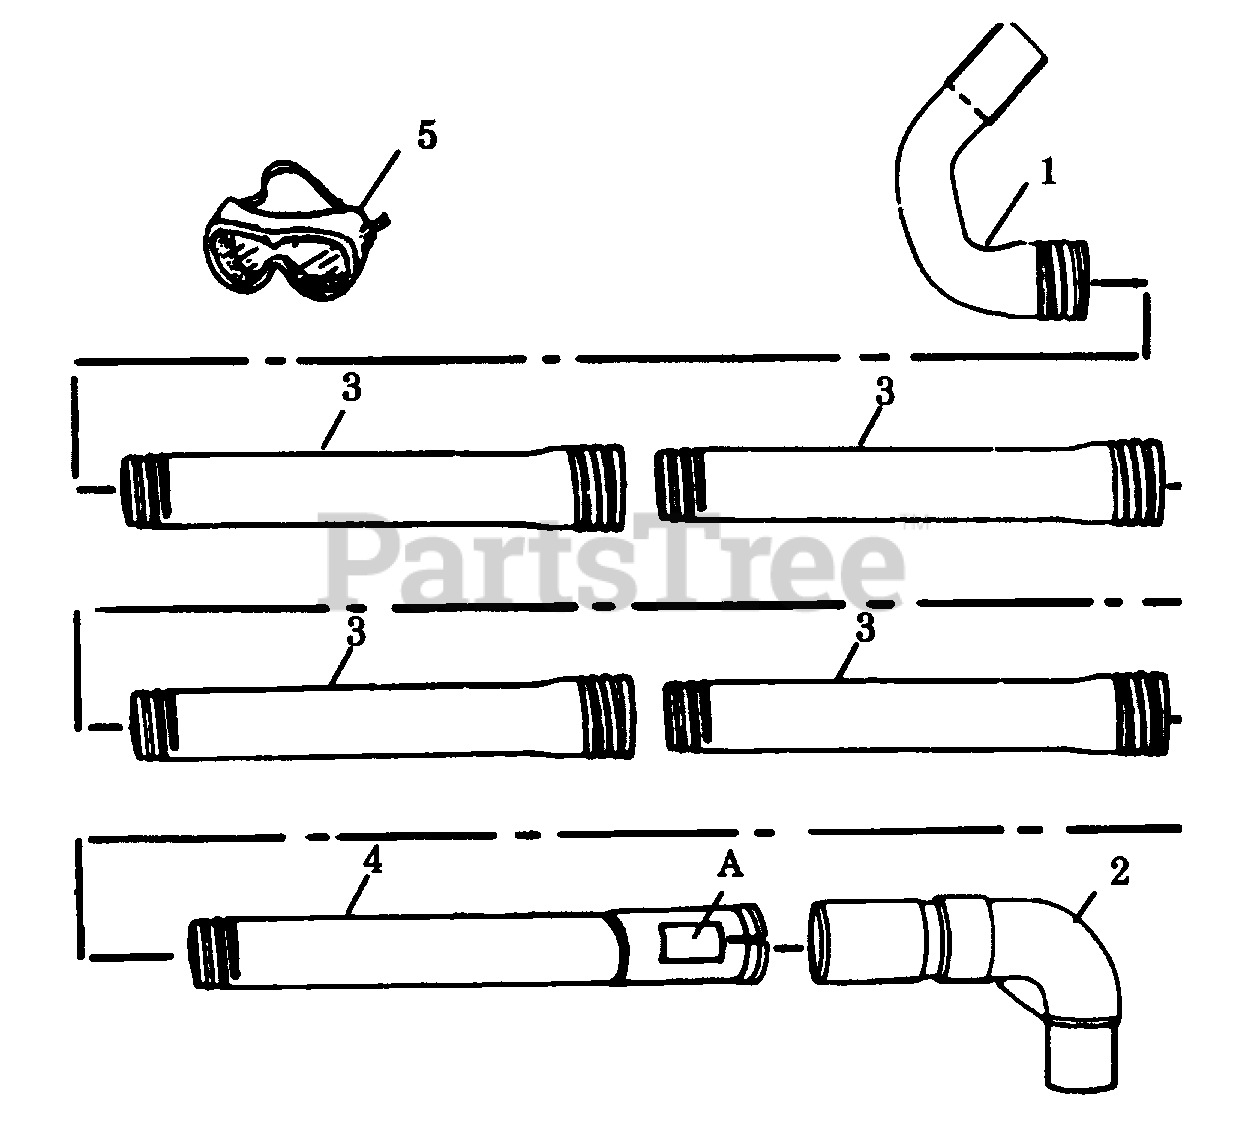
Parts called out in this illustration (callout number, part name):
3	Extension Tube
4	Pivot Tube
5	Goggles
A	Warning Decal
